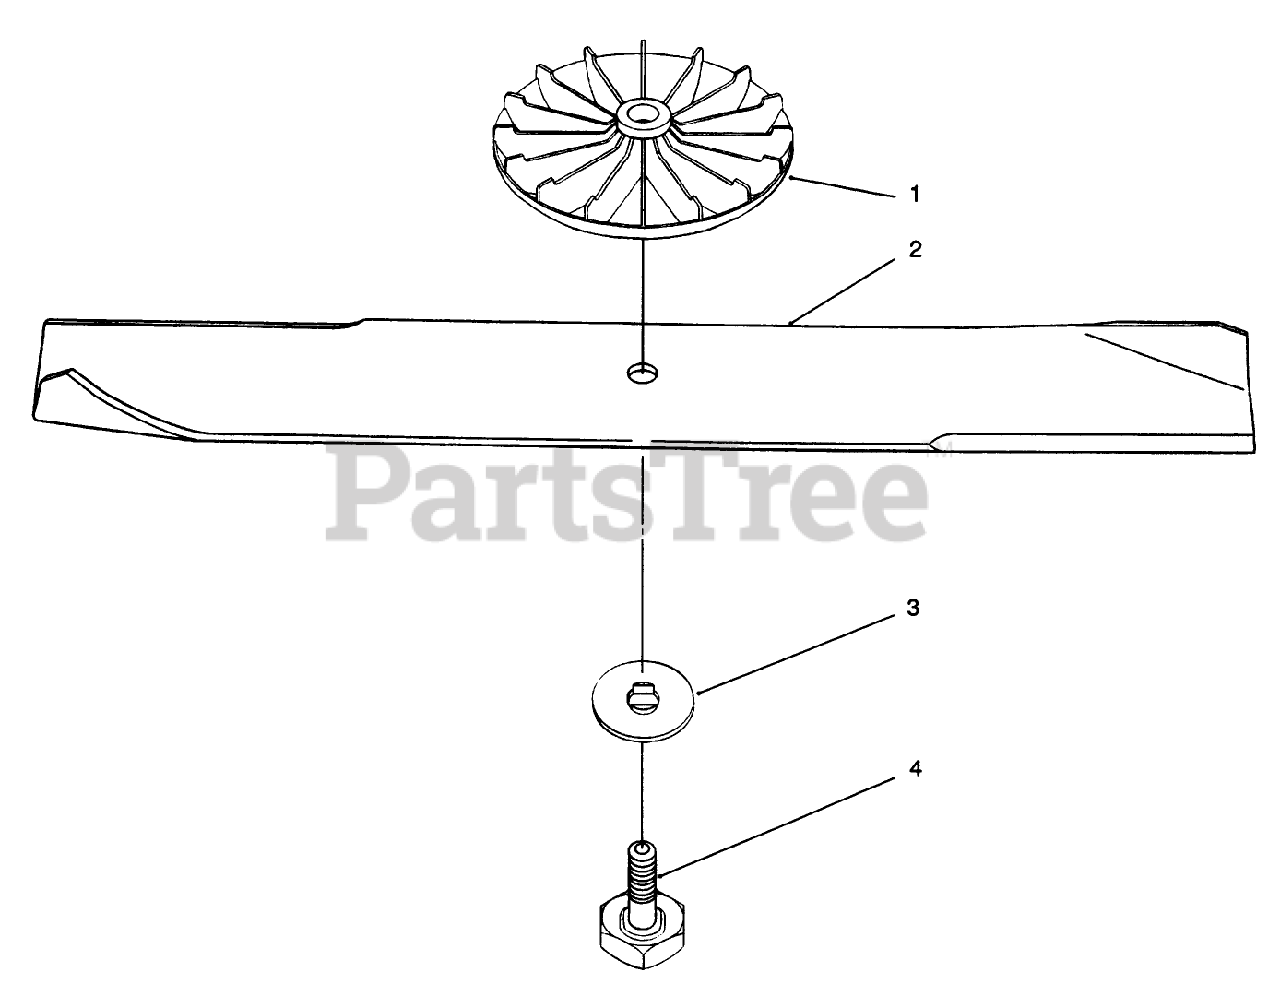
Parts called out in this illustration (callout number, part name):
1	RETAINER - BLADE
2	BLADE
3	CARRIER - BLADE
4	SCREW - COVERED BLADE
